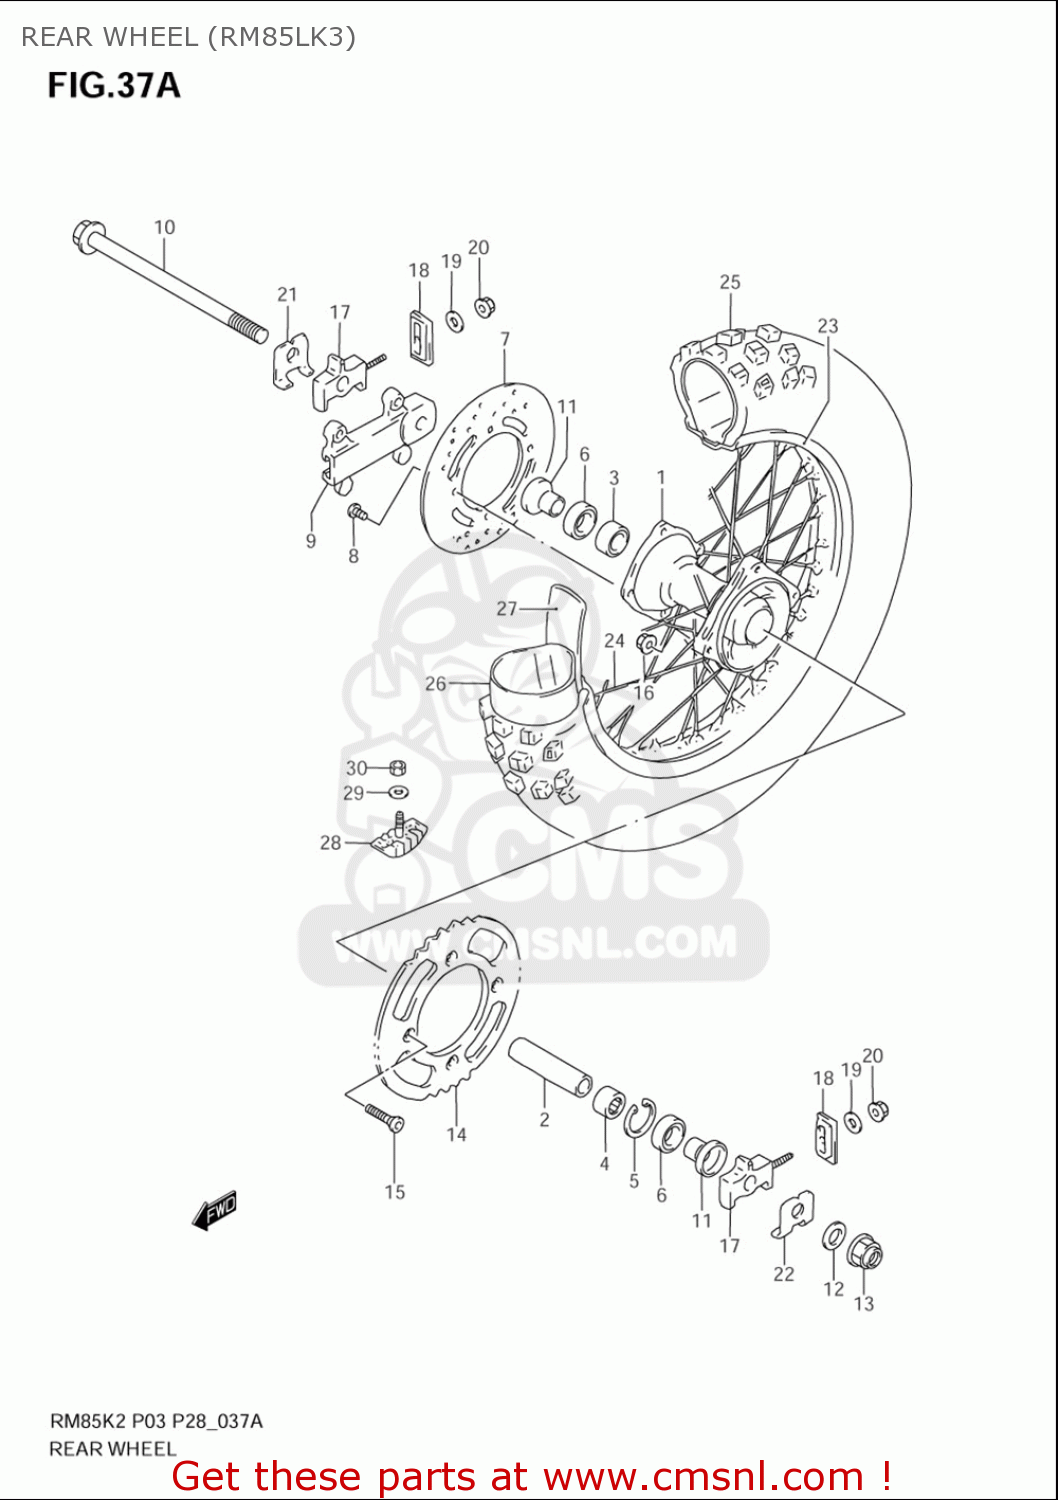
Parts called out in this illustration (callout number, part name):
1	HUB,RR WHEEL
2	SPACER,RR HUB BEARING
3	BEARING
4	BEARING(15X35X11)
5	CIRCLIP
6	SEAL,OIL(20X35X7)
7	DISC,RR BRAKE
8	SCREW
9	BRACKET,RR AXLE
10	AXLE,RR
11	SPACER,RR AXLE
12	WASHER
13	NUT
14	SPROCKET,RR(47T)
15	BOLT(8X30.5)
16	NUT
17	ADJUSTER,CHAIN
18	PLATE,CHAIN ADJUSTER
19	WASHER
20	NUT 6MM
21	WASHER,CHAIN ADJUSTER RH
22	WASHER,CHAIN ADJUSTER,L
23	RIM,RR WHEEL(1.60X16)
24	SPOKE ASSY,RR WHEEL
25	TIRE,RR(90/100 16 52M D737)
26	TUBE ASSY,WHEEL INNER
27	PROTECTOR, INNER TUBE
28	STOPPER,BEAD(1.85)
29	WASHER
30	NUT
